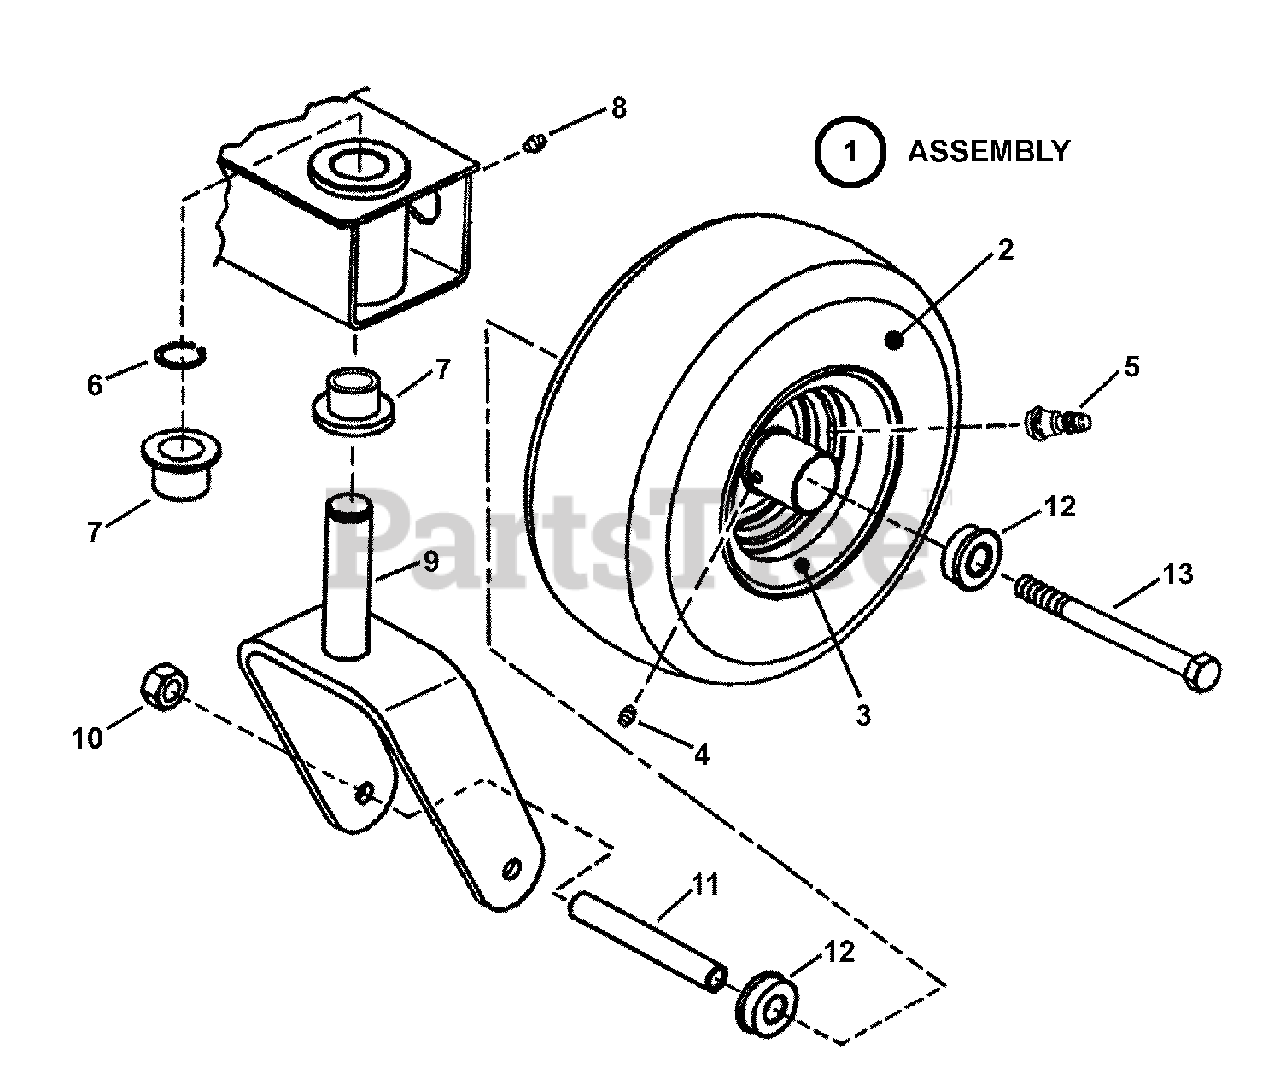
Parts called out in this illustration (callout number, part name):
1	ASSEMBLY, Front Wheel & Tire (Complete) (Includes Items 2 thru 5)
2	TIRE, 11 x 4.00-5, Smooth Tread
3	RIM, 5.00 Dia. x 3.00
4	FITTING, Lube (45° 8Mx1M)
5	VALVE STEM, Air (Snap-in)
6	RING, 1" External Retaining
7	BUSHING, Caster
8	LUBE FITTING, Straight (press-fit for .187 dia. Hole)
9	WELDMENT, Pivot Yoke, Caster
10	NUT, 7/16-14 Hex Center Lock, GR5 or B
11	TUBE, 5/8 O.D. x 14 Ga x 4.51
12	BEARING, Ball, 5/8 x 1-3/8"
13	SCREW, 7/16-14 x 6" Hex Head Cap, GR5
